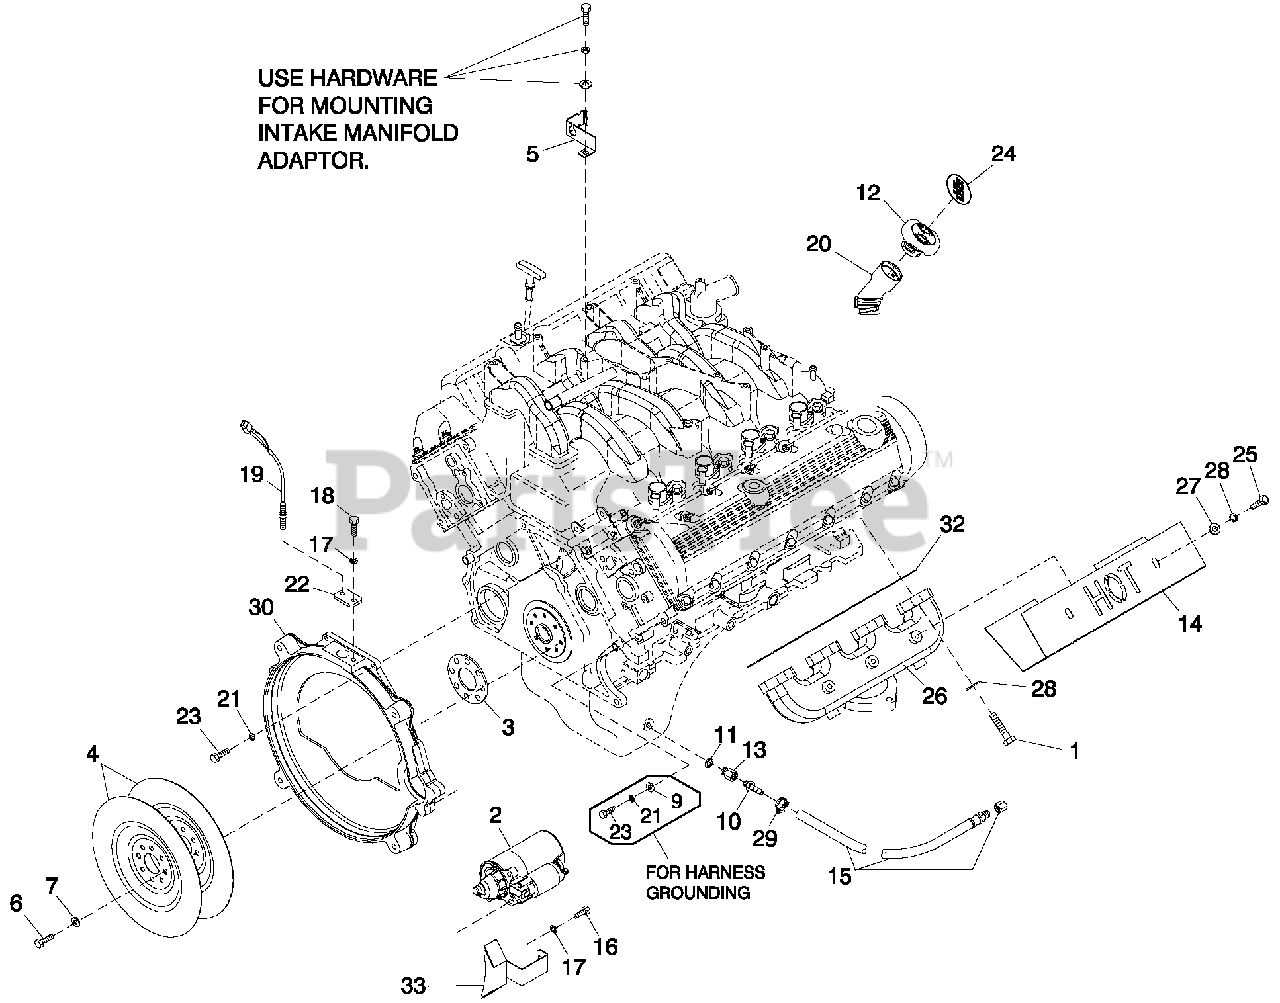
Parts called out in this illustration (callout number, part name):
1	SCREW SHC M8-1.25X 35 SS
2	STARTER MOTOR 12V
3	SPACER FLEXPLATE 5.4L/6.8L (1800 RPM ONLY)
4	FLEX PLATE 2 POLE 5.4L/6.8L (1800 RPM UNITS ONLY)
5	BRACKET, SIGNAL CONDITIONER
6	SCREW HHC M10-1.0 X 25 G10.9
7	WASHER FLAT .43X1.00
9	WASHER FLAT 3/8-M10 ZINC
10	BARBED STR 3/8 NPT X 3/8
11	WASHER NYLON .565
12	CAP, OIL FILLER
13	ADAPTER M14-1.50X 3/8 NPT
14	HEAT SHLD EXHAUST MANIFOLD
15	HOSE DRAIN ASSY 28"
16	SCREW SHC M8-1.25 X 30 G12.9
17	WASHER LOCK M8-5/16
18	SCREW HHC M8-1.25X20 G8.8
19	ASSY MAGPICKUP (3/8-24 MALE)
20	NECK OIL FILLER
21	WASHER LOCK M10
22	PLATE MAG PICK-UP ADAPTOR
23	SCREW SHC M10-1.5 X 55 G12.9
24	DECAL REFER TO OWNERS MANUAL
25	SCREW HHC 5/16-18 X 1/2 SSTL
26	MACHINED MANIFOLD EXHAUST 5.4L
27	WASHER FLAT M8 SS
28	WASHER LOCK M8 SSTL
29	CLAMP HOSE .38-.87
30	ENGINE ADAPTER 5.4L/6.8L
32	GASKET, EXHAUST MANIFOLD
33	COVER STARTER 5.4/6.8L G3
